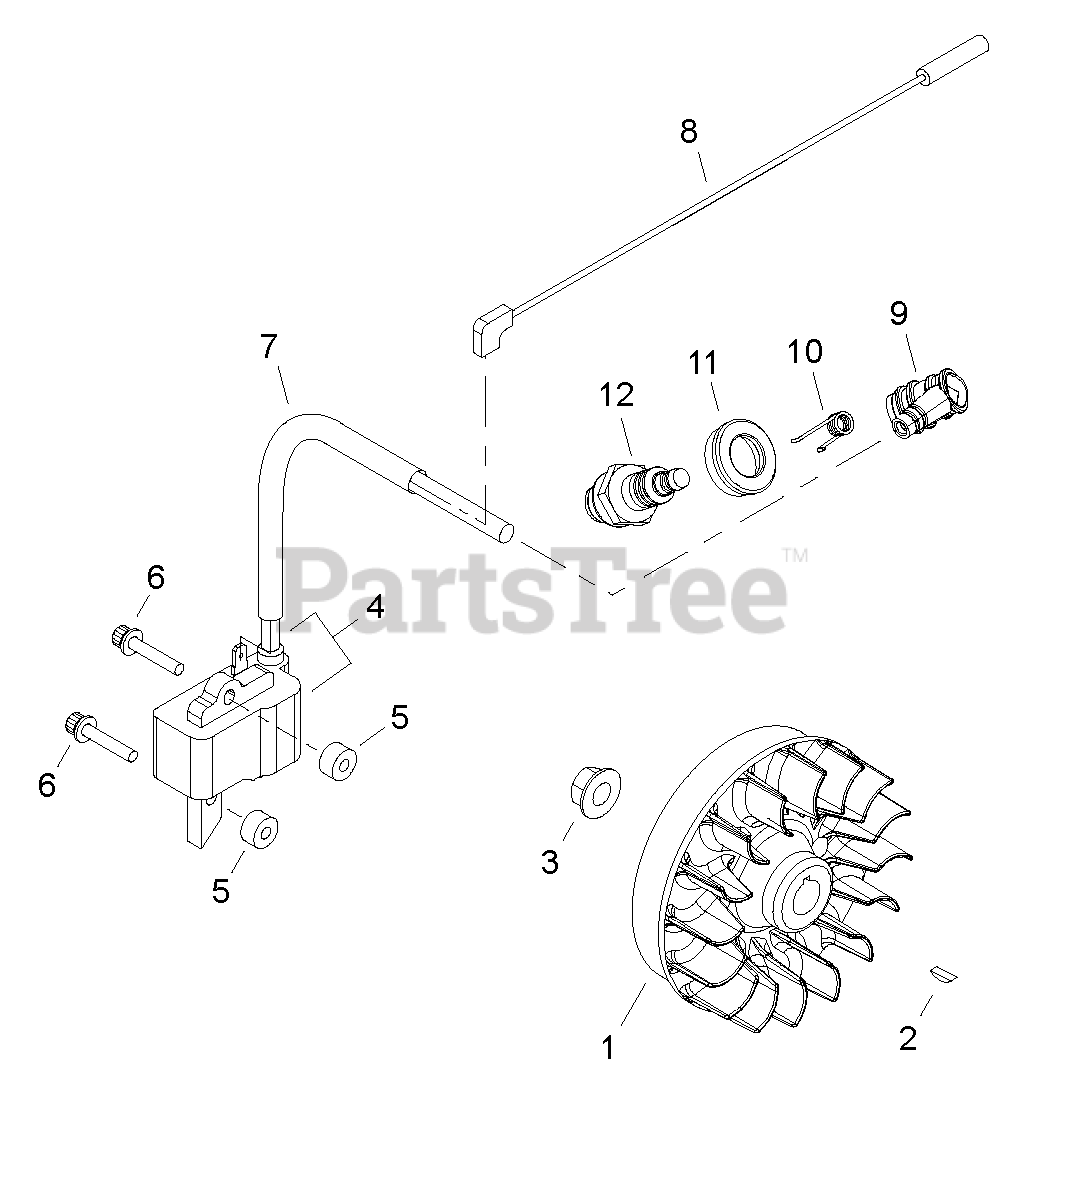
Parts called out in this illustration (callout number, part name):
1	FLYWHEEL
2	KEY, WOODRUFF 3×10
3	NUT M8
4	COIL, IGNITION
5	INSULATOR 4.2×11×6
6	BOLT, ADHESIVE M4×20
7	TUBE, IGNITION COIL
8	LEAD - IGNITION L= 215
9	CAP, SPARK PLUG
10	SEAL, SPARK PLUG
11	TERMINAL, SPARK PLUG
12	SPARK PLUG - BPMR6A
